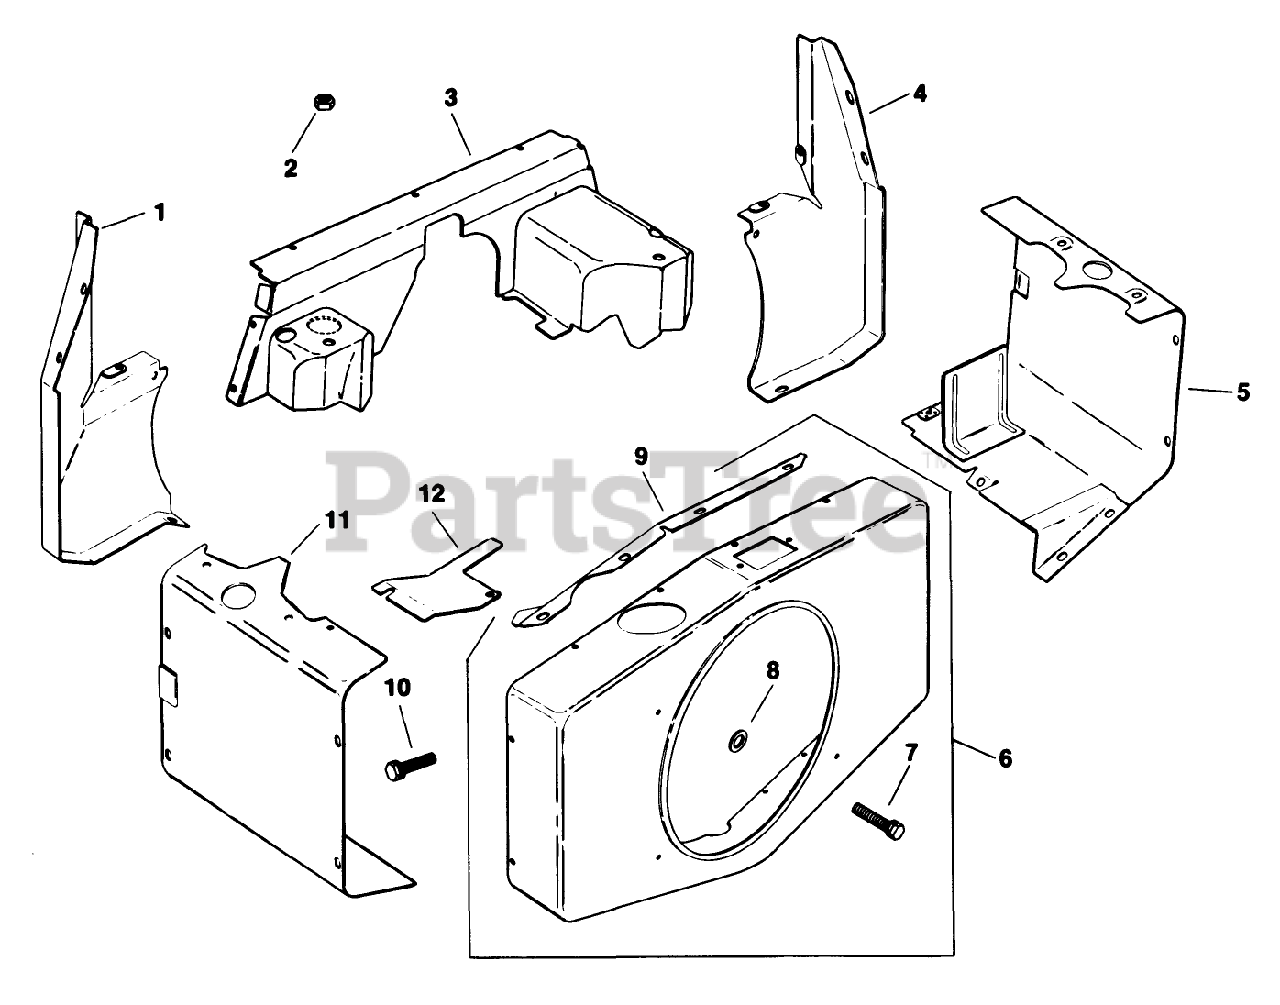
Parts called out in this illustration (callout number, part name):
1	Duct-#1 Side Air
2	Nut
3	Cover-Air Duct
4	Duct-#2 Side Air
5	Baffle-#1 Cylinder Head
6	Kit-Blower Housing (Incl. Ref. #7, 8 & 12)
7	Screw-H.C
9	Screw
10	Baffle-Cylinder Head
11	Baffle-Cylinder Head
12	Support-Upper Housing
